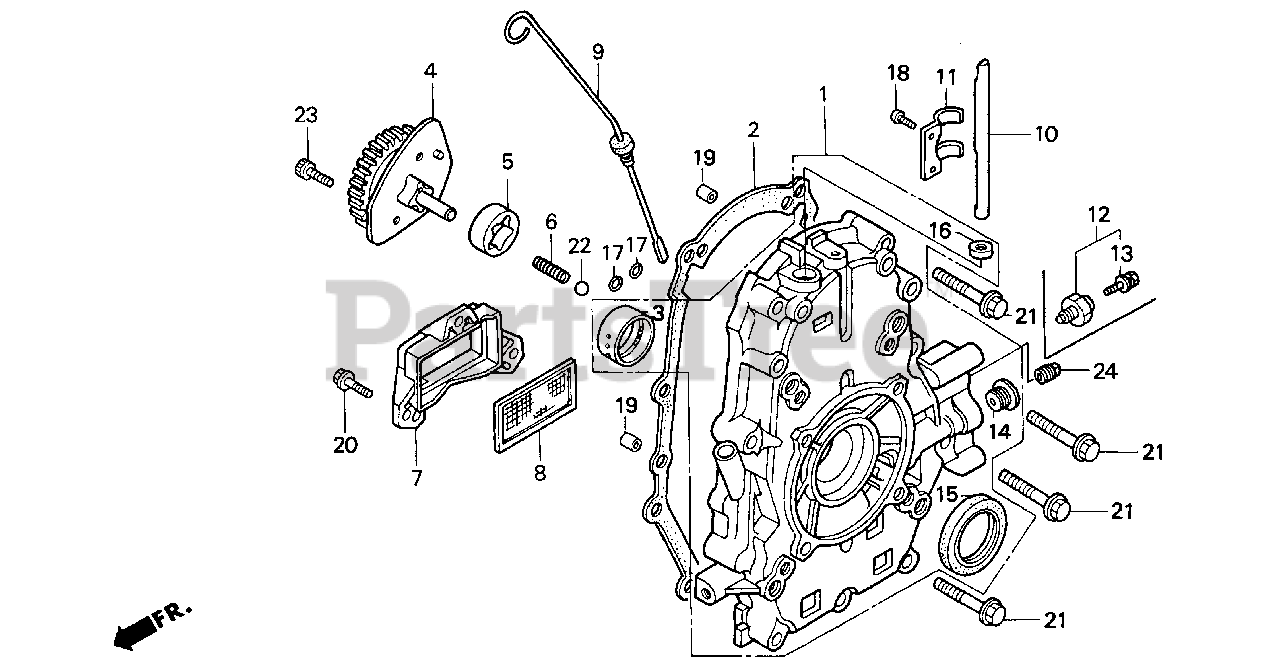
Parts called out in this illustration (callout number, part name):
1	COVER ASSY., CRANKCASE
2	GASKET, CASE COVER
3	BEARING A, MAIN (TO SELECT CORRECT BEARING, SEE THE SERVICE MANUAL.)
3	BEARING B, MAIN (TO SELECT CORRECT BEARING, SEE THE SERVICE MANUAL.)
3	BEARING C, MAIN (TO SELECT CORRECT BEARING, SEE THE SERVICE MANUAL.)
4	COVER ASSY., OIL PUMP
5	ROTOR, OIL PUMP (OUTER)
6	SPRING, RELIEF VALVE
7	COVER, OIL FILTER
8	SCREEN, OIL FILTER
9	DIPSTICK, OIL
10	SHAFT, GOVERNOR ARM
11	FORK, GOVERNOR
12	SWITCH, OIL PRESSURE
13	SCREW-WASHER (4X8)
14	BOLT, SEALING
15	OIL SEAL (38X58X11)
16	OIL SEAL (10X16X4.5)
17	O-RING (13X3.0)
18	SCREW, PAN (5X10)
19	PIN A, DOWEL (8X14)
20	BOLT, FLANGE (6X20)
21	BOLT, FLANGE (8X50)
22	BALL, STEEL (#12) (3/8)
23	BOLT, SOCKET (6X16)
